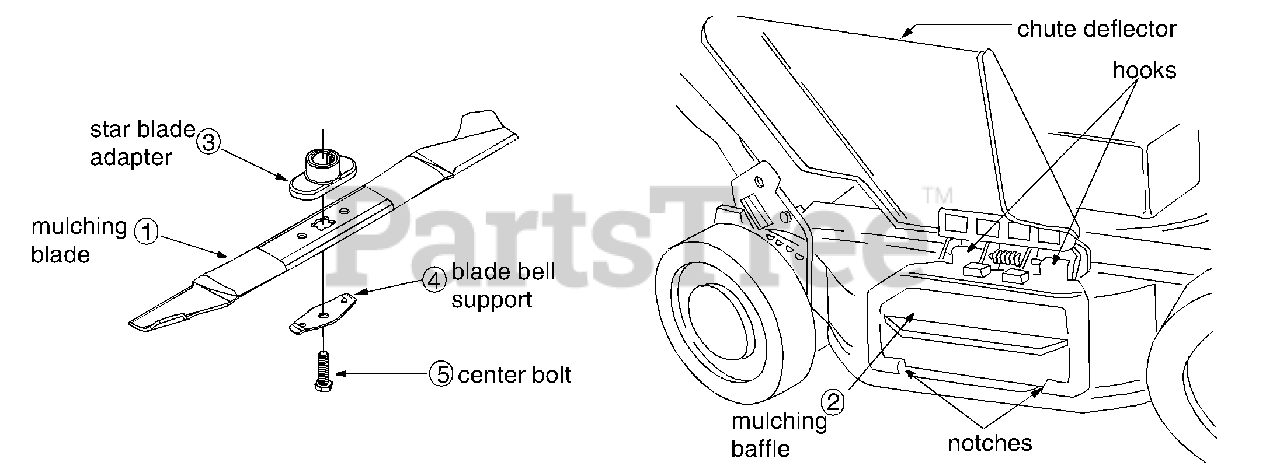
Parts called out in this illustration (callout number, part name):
1	20" Mulching blade (190-114-000)
1	22" Mulching blade (190-115-000)
2	Mulching baffle
3	Star blade adapter
4	Blade bell support
5	Center Bolt
